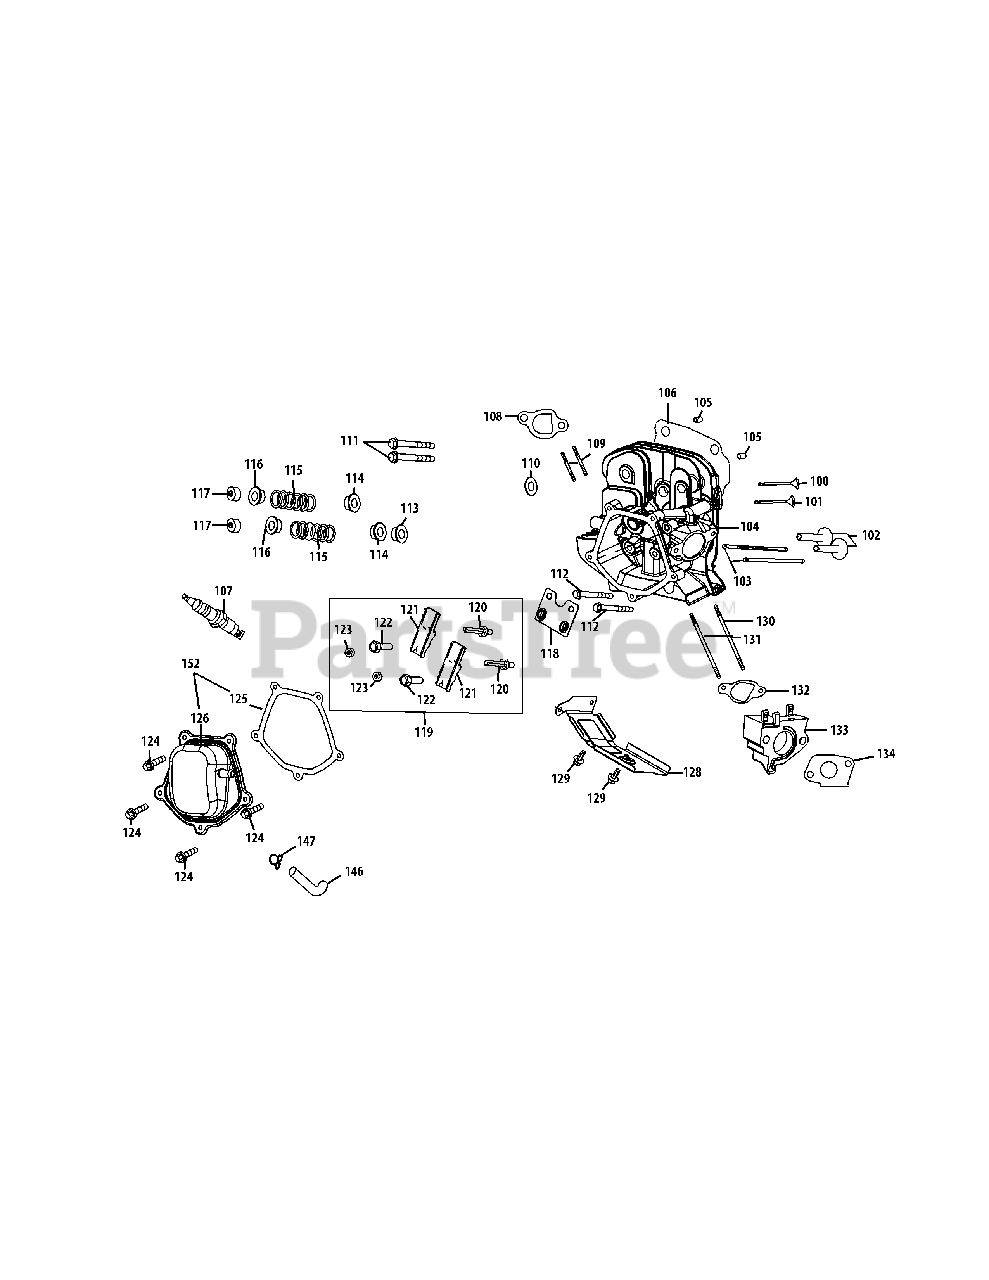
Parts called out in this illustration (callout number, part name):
100	Exhaust Valve
101	Intake Valve
102	Tappet
103	Push Rod Kit
104	Cylinder Head Ass'y
105	Dowel Pin 12×20
106	Gasket, Cylinder Head
107	Spark Plug
108	Muffler Gasket
109	Muffler Stud M8×48.5
110	Muffler Stud Assembly
110	Cupped Washer
111	Head Bolt
112	Bolt M10×1.25×87
113	Intake Valve Seal
114	Valve Spring Retainer
115	Valve Spring
116	Retainer, Ex.Valve Spring
117	Adjuster, Exh Valve
118	Push Rod Guide
119	Rocker Arm Assembly
120	Bolt, Pivot
121	Rocker Arm
122	Adjusting Nut ,Valve
123	Nut, Pivot Locking
124	Valve Cover Bolt
125	Valve Cover Gasket
126	Valve Cover
128	Cylinder Baffle
129	Bolt M6×12
130	Carb Stud M6-8×98
131	Carb Stud M6-8×118
132	Carburetor Insulator Gasket
133	Carburetor Insulator
134	Carburetor Gasket
146	Breather Hose
152	Valve Cover Kit
